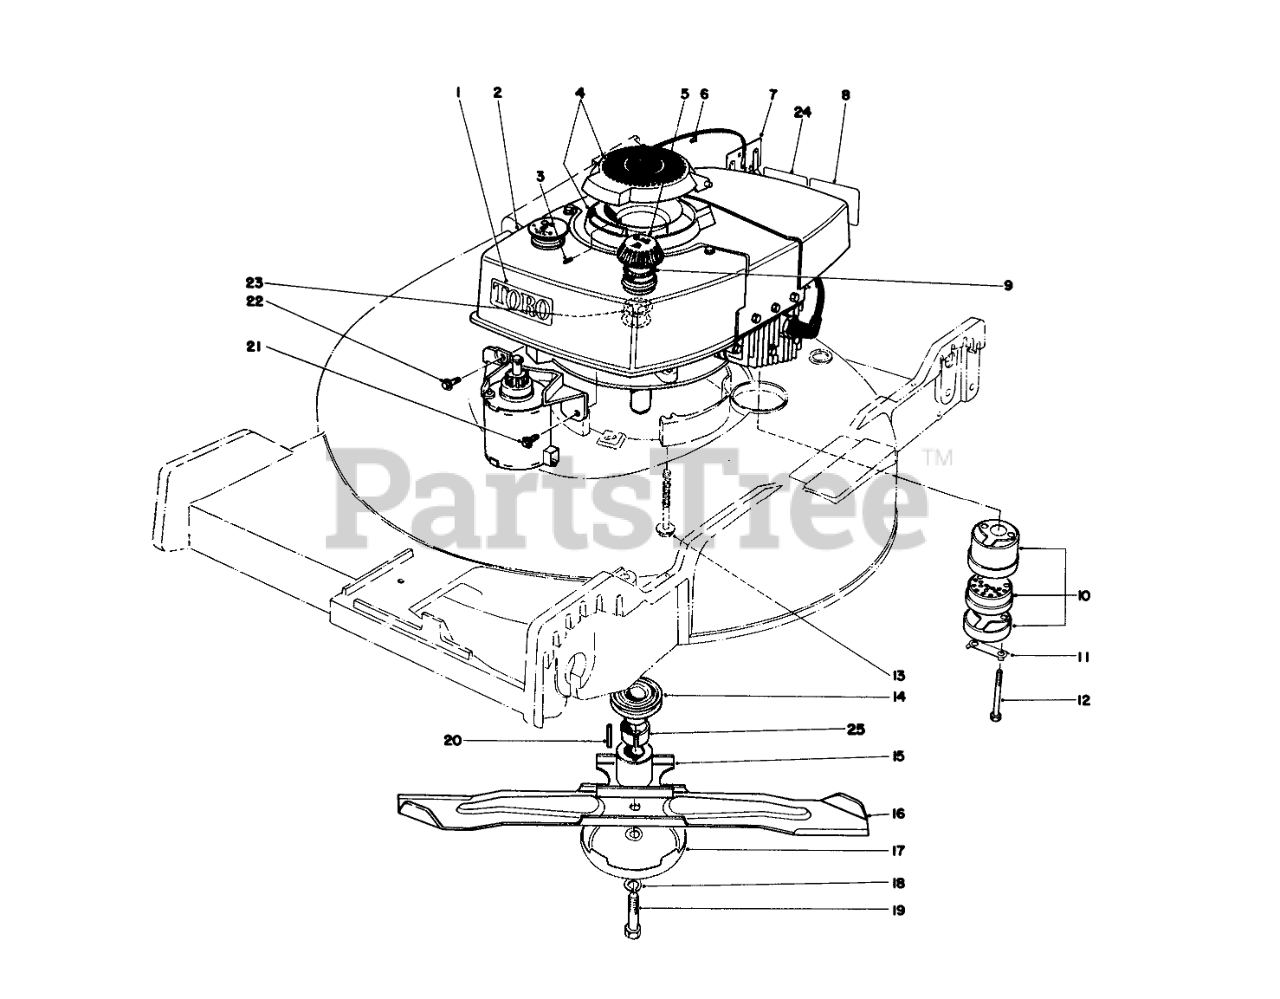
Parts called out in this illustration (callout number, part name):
1	Decal Toro
2	Engine
3	SPRING PIN
4	Cover
5	WIRE CLIP
6	Gas Cap Assembly (Incl. Ref. #9 & 23)
7	SWITCH & TERM BLK CVR
8	Decal Maintenance
9	GASKET
10	Muffler Assembly (Incl. Ref. #11 & 12)
11	CLIP - LOCKING
12	SCREW-HH
13	3/8-16 X 2-3/4 CAPSCR
14	PULLEY DRIVER
15	BLADE RETAINER WA
16	Blade
17	AntiScalp Cup
18	WASHER-LOCK
19	BLADE SCREW
20	KEY-SQUARE
21	SCREW
22	Screw
23	GAS CAP BAFFLE
24	Decal-Maintenance
25	Pulley Spacer
